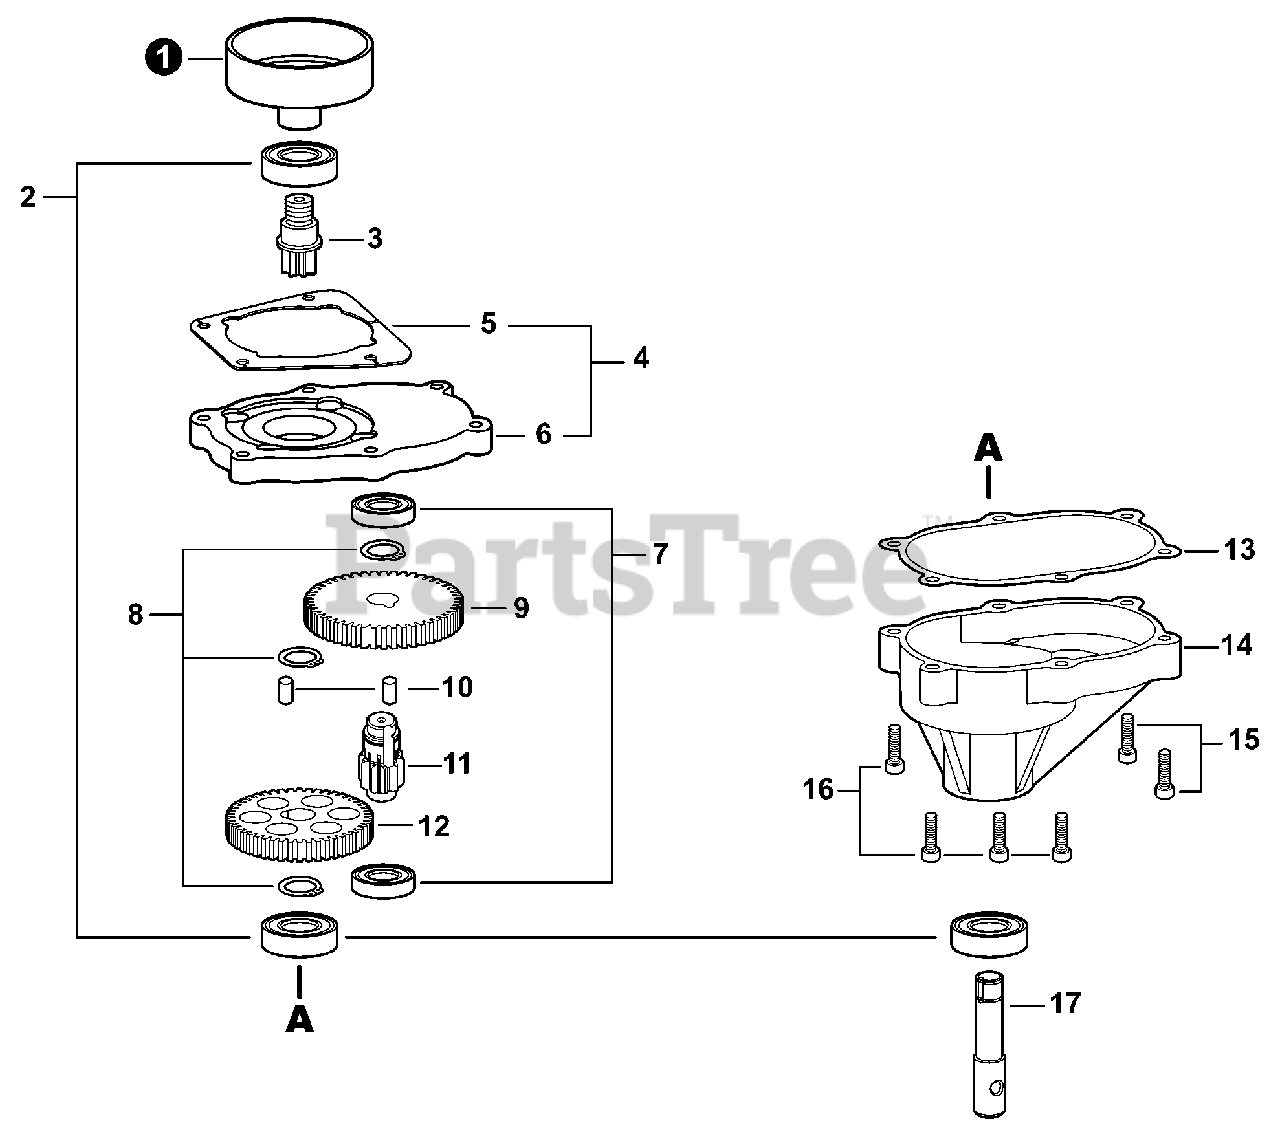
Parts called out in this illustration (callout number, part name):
1	DRUM, CLUTCH
2	BEARING, BALL
3	SHAFT, GEAR
4	GEAR CASE SET
5	SHIM, GEAR CASE
6	CASE, GEAR
7	BEARING, BALL
8	RING, SNAP
9	GEAR, SPUR
11	SHAFT, GEAR
12	GEAR, SPUR
13	GASKET, GEAR CASE
14	COVER, GEAR CASE
17	DRIVESHAFT
